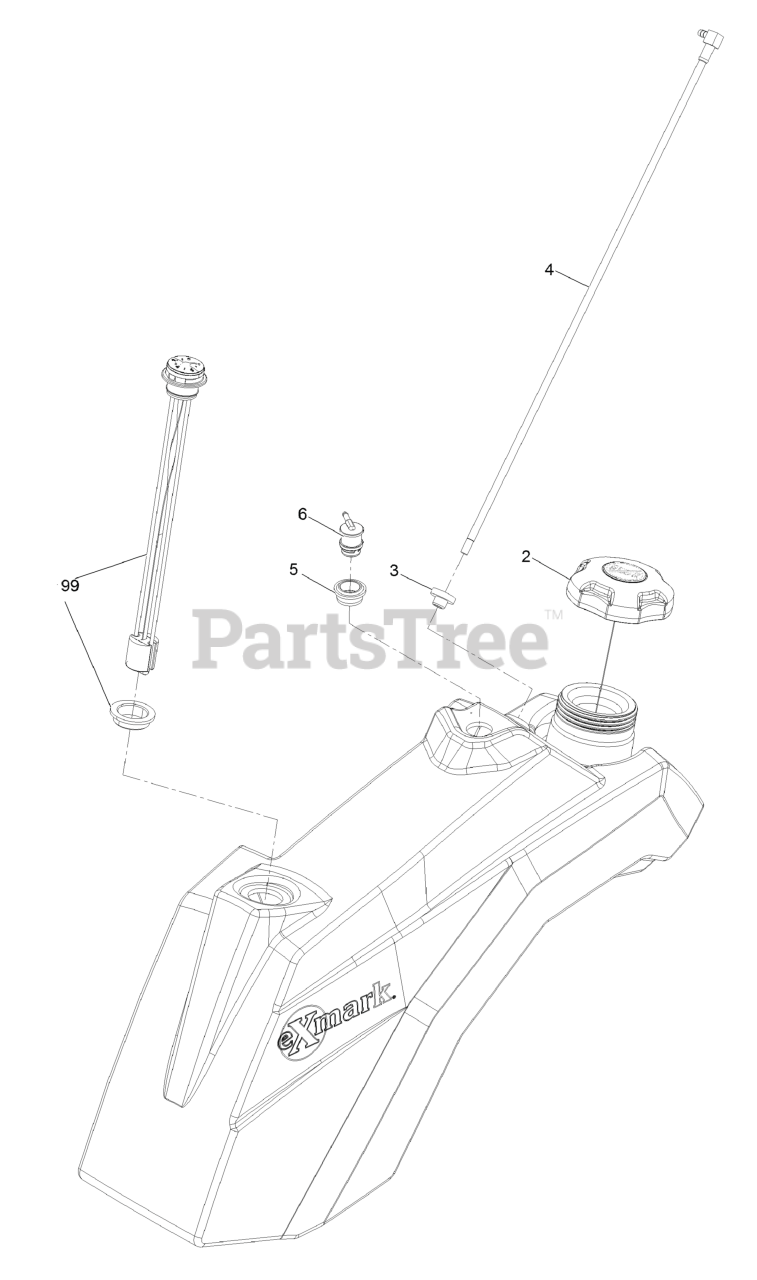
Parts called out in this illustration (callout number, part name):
2	CAP-FUEL, RATCHETING
3	BUSHING
4	STRAW, FUEL, LONG
5	GROMMET
6	VALVE-VENT, FUEL
99	KIT-FUEL GAUGE REPLACEMENT
